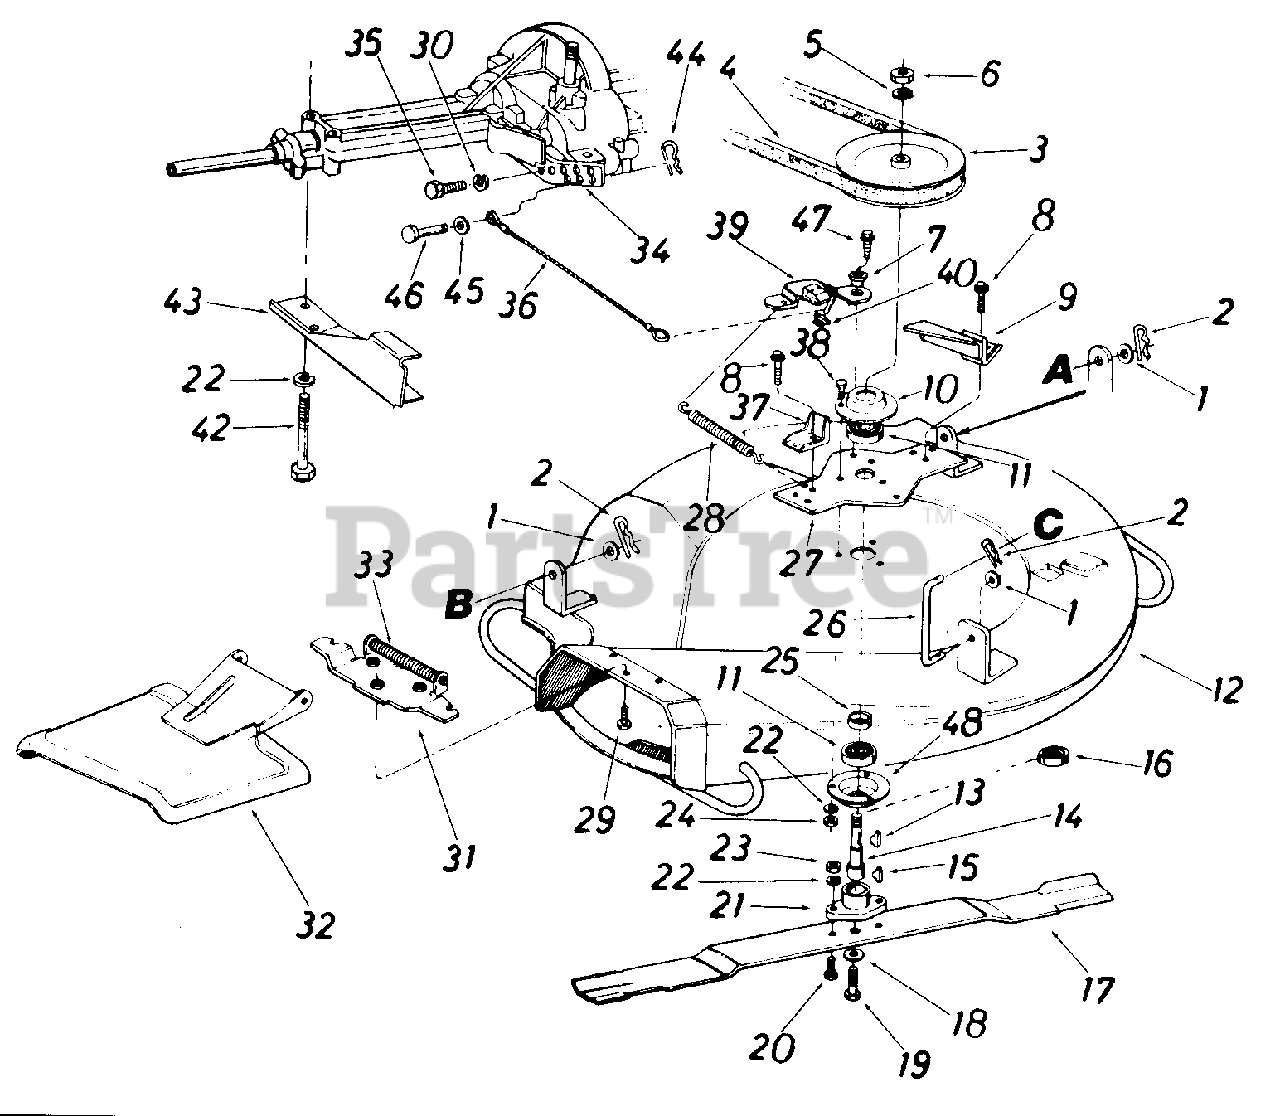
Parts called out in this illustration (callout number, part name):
1	Fl-Wash..385" I.D. c .87" O.D. x .06
2	Cotter Pin 1/8" Dia. x 1.00"*
3	Deck Pulley 6.0" O.D.
4	"V"-Belt 1/2 " x 52" Lg.
5	Fl-Wash. 5/8" I.D.*
6	Hex Jam Nut 5/8-11 Thd.*
7	Shoulder Spacer
8	Hex Wash. Hd. Scr. 5/16-18 x.62" Lg.
9	Belt Guard Ass'y.
10	Bearing Housing 1.85" I.D.
11	Ball Brg. .787" I.D. x 1.85" O.D. x .551
12	26" Deck Ass'y.
13	#61 Hi-Pro Key 3/16" x 5/8" Dia.
14	Blade Spindle
15	#6 Hi-Pro Key 5/32" x 5/8" Dia.
16	Bearing Shield
17	26" Blade
18	L-Wash. 3/8" I.D. H.D.
19	Hex Bolt 3/8-24 x 1.50" Lg. (Grade 5)
20	Hex Bolt 5/16-24 x 1.00" Lg. (Grade 5)
21	Blade Adapter Kit
22	L-Wash. 5/16" I.D.*
23	Hex N ut 5/16-24 Thd.*
24	Hex Nut 5/16-18 Thd.*
25	Spacer.836" I.D. x 1.01" O.D. x .320
26	Deck Link 3.9" Lg.
27	Belt Guard Plate Ass'y.
28	Spring .38" O.D. x 3.25" Lg.
29	Hex Self-Tap Scr. 1/4 " x .50" Lg.
30	L-Wash. 1/4" I.D.*
31	Adapter Ass'y. Chute
32	Chute Deflector Ass'y. Comp.
33	Torsion Spring
34	Lower Inside Belt Guard
35	Hex Bolt 1/4-20 x .62" Lg.*
36	Brake Cable Ass'y.
37	Belt Keeper Ass'y.
38	Hex Sems Bolt 5/16-18 x 1.00" Lg.
39	Blade Brake Brkt. Ass'y.
40	Cap Speed Nut 1/4" Rod
42	Hex Bolt 5/16-18 x 2.75"
43	Lower Outside Engine Belt Guard
44	Hairpin Cotter
45	Fl-Wash. 1/4" I.D. x .50" O.D.
46	Clevis Pin 1/4" x 1/2"
47	Self-Tap Scr. 3/8 x .75" Lg.
48	Open Brg. Housing 1.85" I.D.
